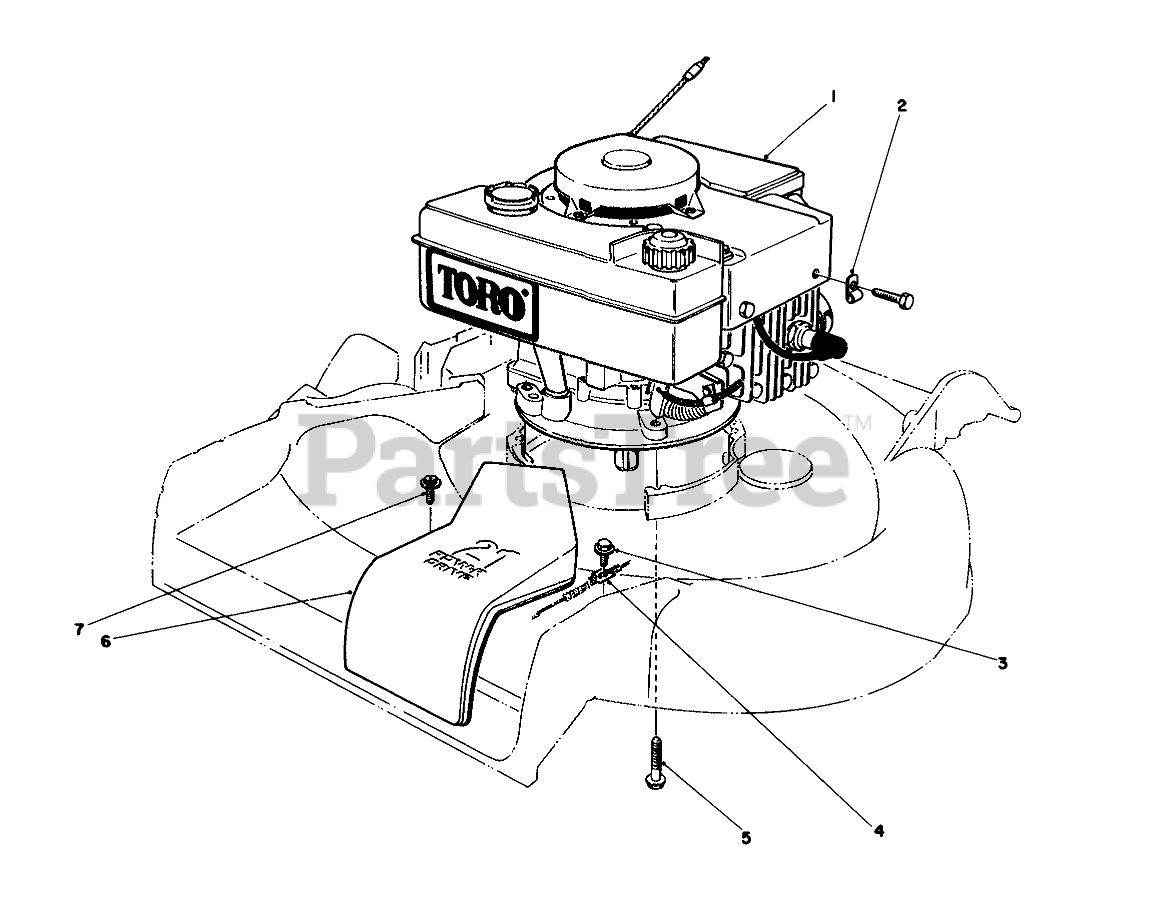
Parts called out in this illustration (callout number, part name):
2	CLAMP
3	SCREW-HWHTF
4	Cable Clamp
5	3/8-16 X 2-3/4 CAPSCR
6	BELT COVER 21" S D
7	SCREW
